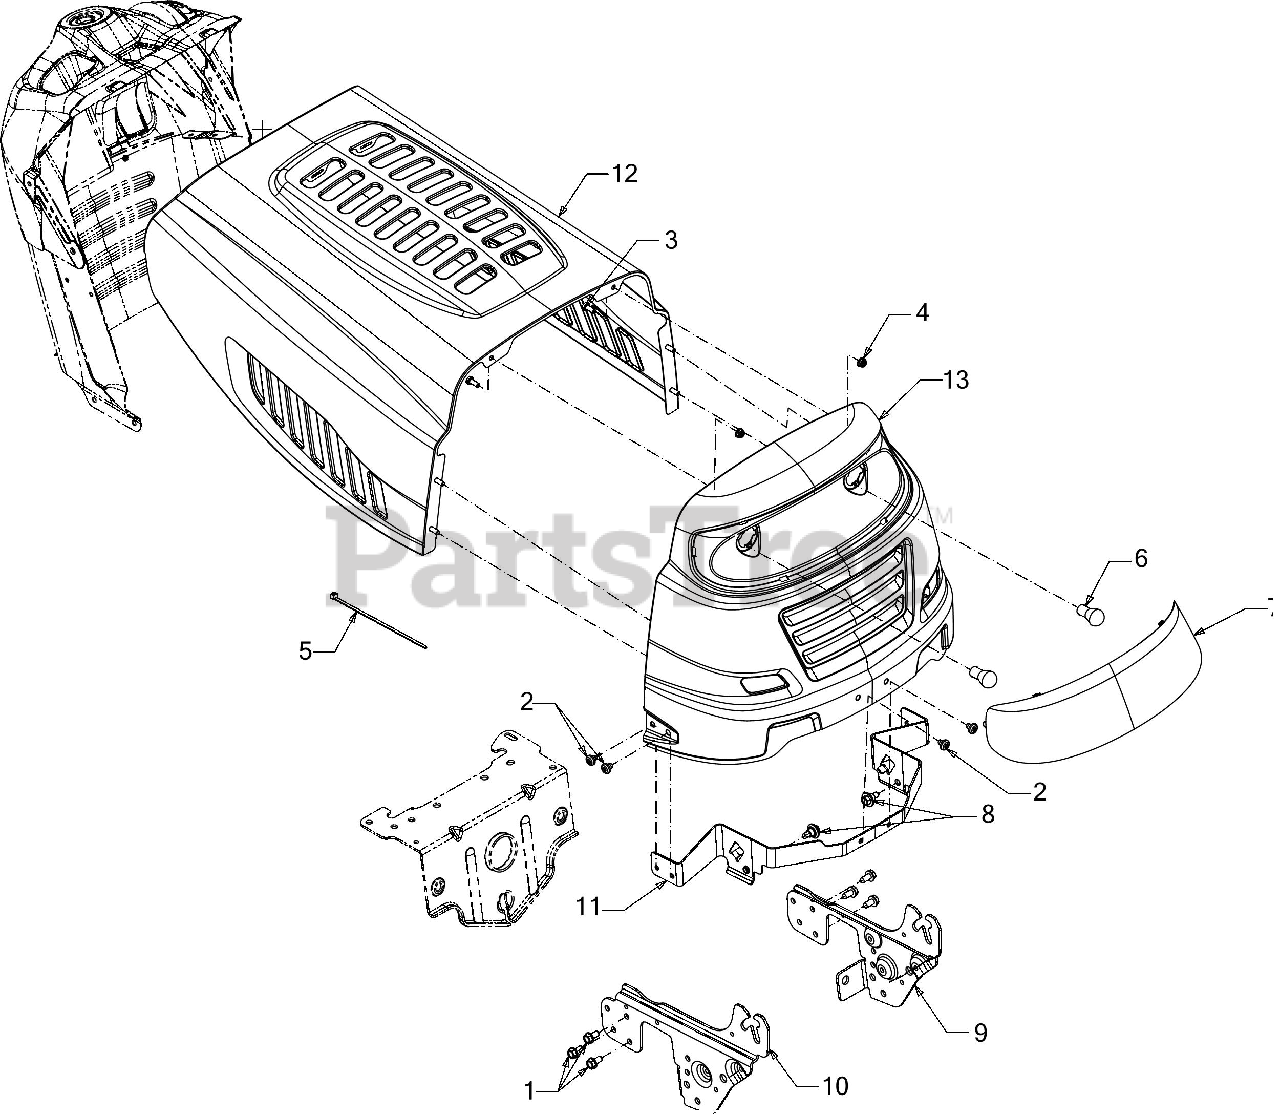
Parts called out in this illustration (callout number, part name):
1	SCREW 5/16-18 x .750
2	SCREW 5/16-18 x .375
3	SCREW 1/4-20 x .620 GR5
4	FLANGE LOCK NUT
5	7" CABLE TIE
6	MINIATUURE BULB 12V
7	GRILL LENS
8	SHOULDER SCREW .43X.29X5/16-18 TT
9	SUPPORT BRACKET (LH)
10	SUPPORT BRACKET (RH)
11	HOOD PIVOT BRACKET
12	HOOD-5-STYLE
13	GRILLE-1 STYLE
